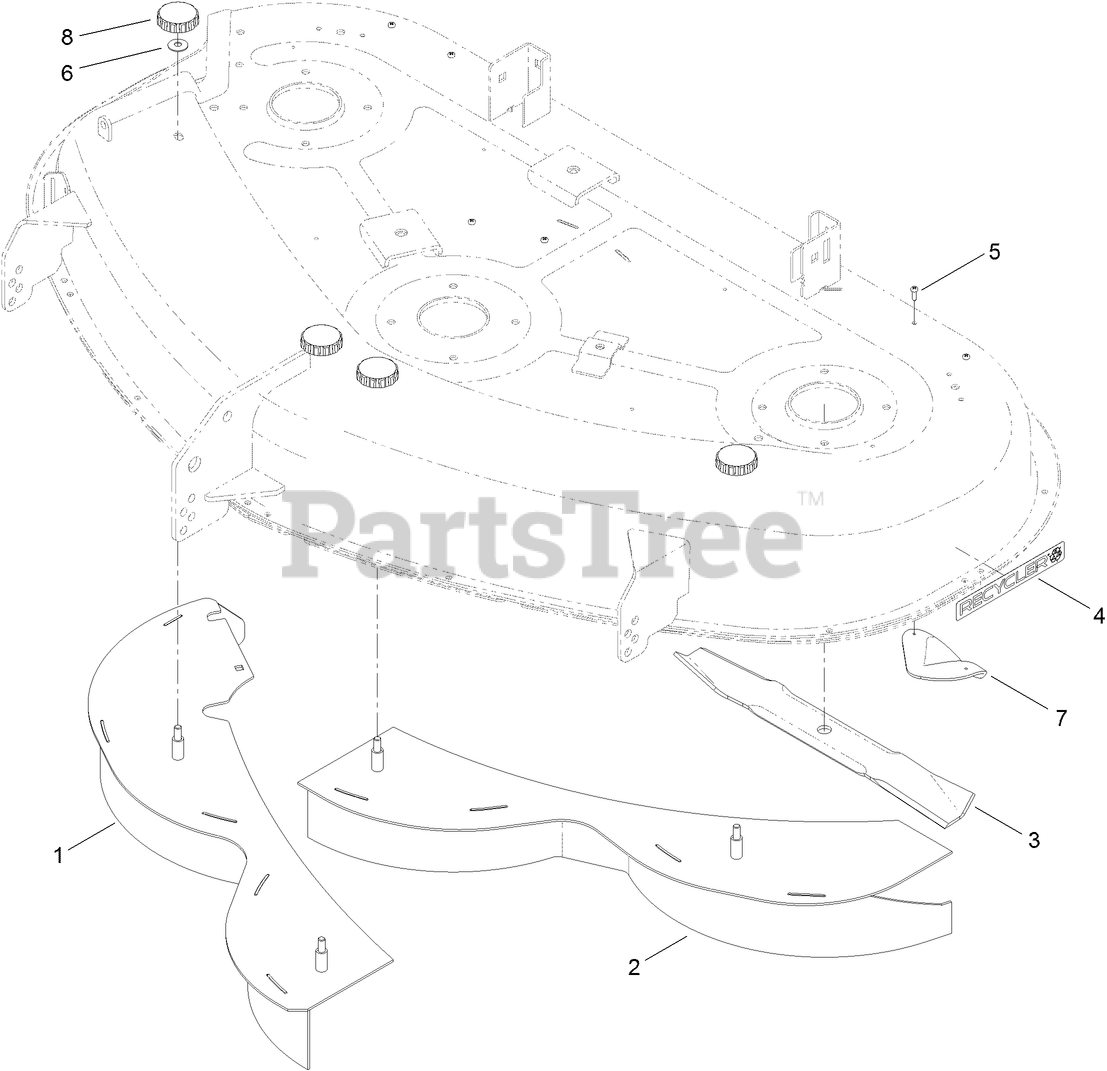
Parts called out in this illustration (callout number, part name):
1	RH BAFFLE ASM
2	LH BAFFLE ASM
3	BLADE-MULCH, 17.50 INCH
4	DECAL-RECYCLER
5	SCREW-PPH
6	WASHER-BELLEVILLE
7	PLATE-KICKER
